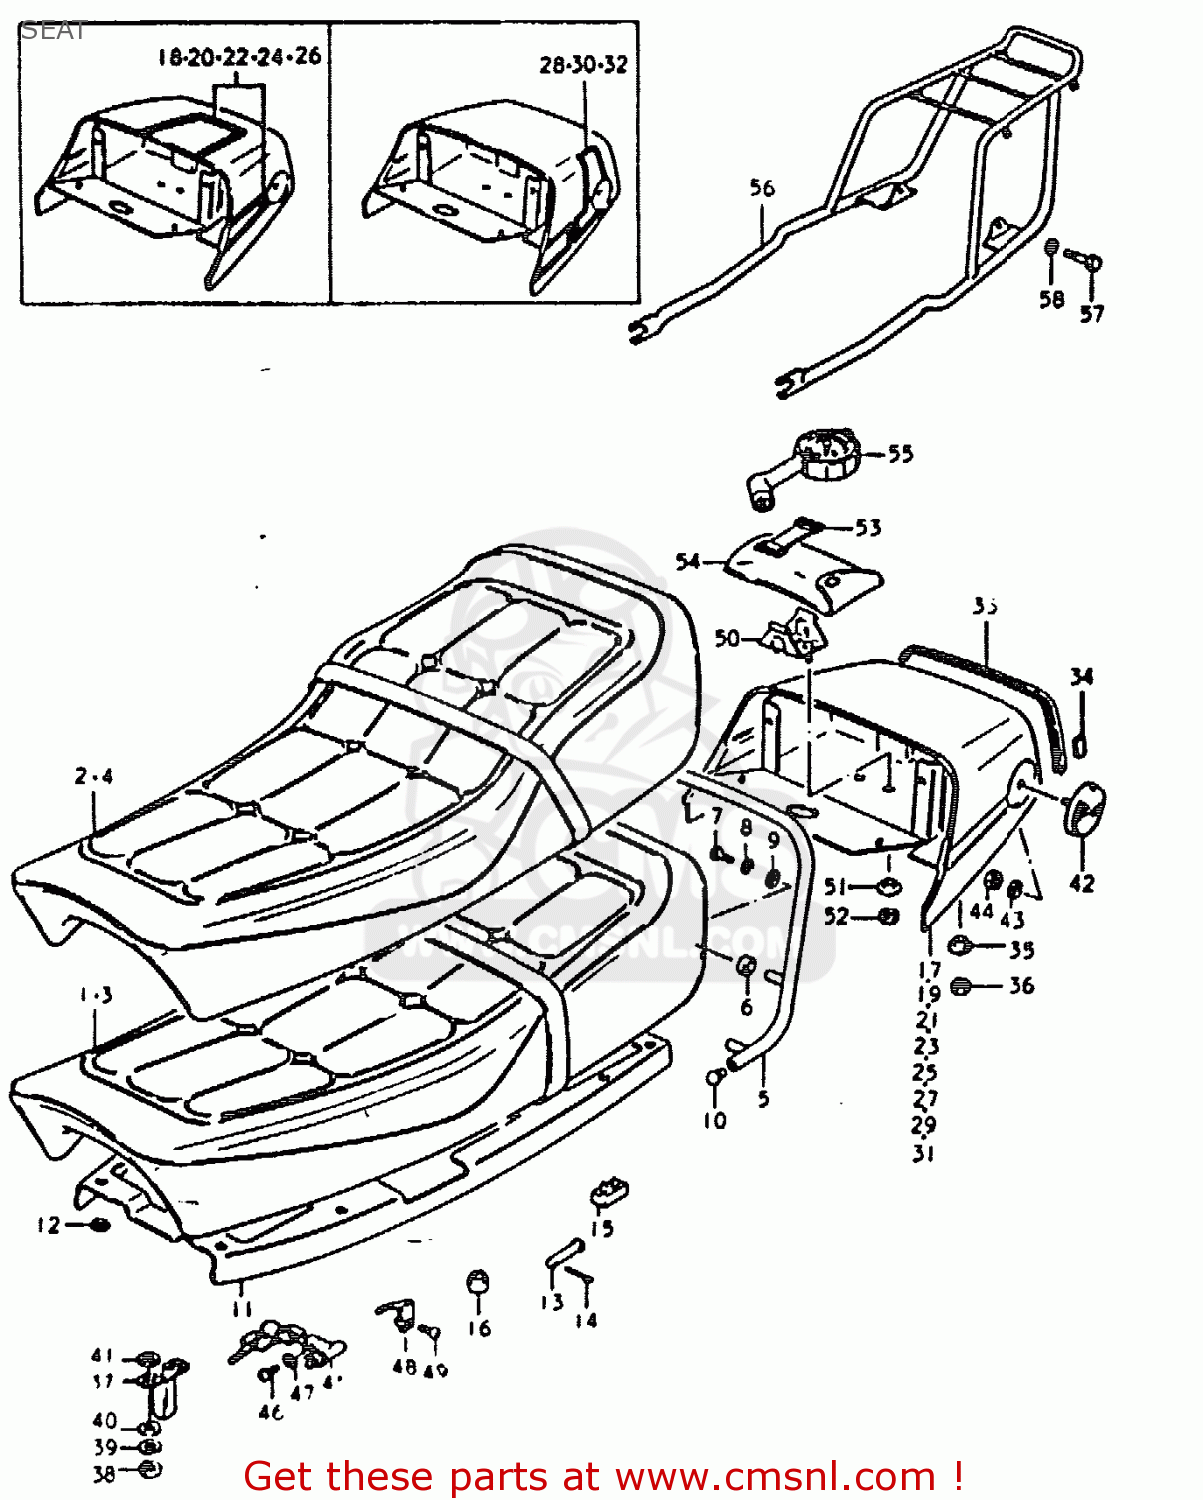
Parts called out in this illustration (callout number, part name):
1	SEAT, FLAT TYPE (WITH BAND)
2	SEAT, STEP TYPE (WITH BAND)
11	PLATE, SEAT LOWER
12	NUT
13	PIN
14	PIN
15	CUSHION
16	CUSHION
27	COVER ASSY, SEAT TAIL
28	TAPE SET
29	COVER ASSY, SEAT TAIL
30	TAPE SET
31	COVER ASSY, SEAT TAIL
32	TAPE SET
33	GROMMET
34	CLIP,SEAT TAIL COVER M
35	WASHER
36	NUT 6MM
37	STRIKER,SEAT LOCK
38	NUT
39	LOCK WASHER
40	WASHER
41	WASHER (6.5X20X1.2)
42	REFLEX REFLECTOR,RR
43	WASHER
44	NUT
45	LOCK ASSY,SEAT
46	SCREW
47	LOCK WASHER
48	SPRING,HELMET HOLDER
49	SCREW
50	HOLDER,TOOL
51	WASHER
52	NUT
53	BAND
54	TOOL SET
55	GAUGE ASSEMBLY,AIR PRESSURE
56	CARRIER
57	BOLT
58	WASHER
